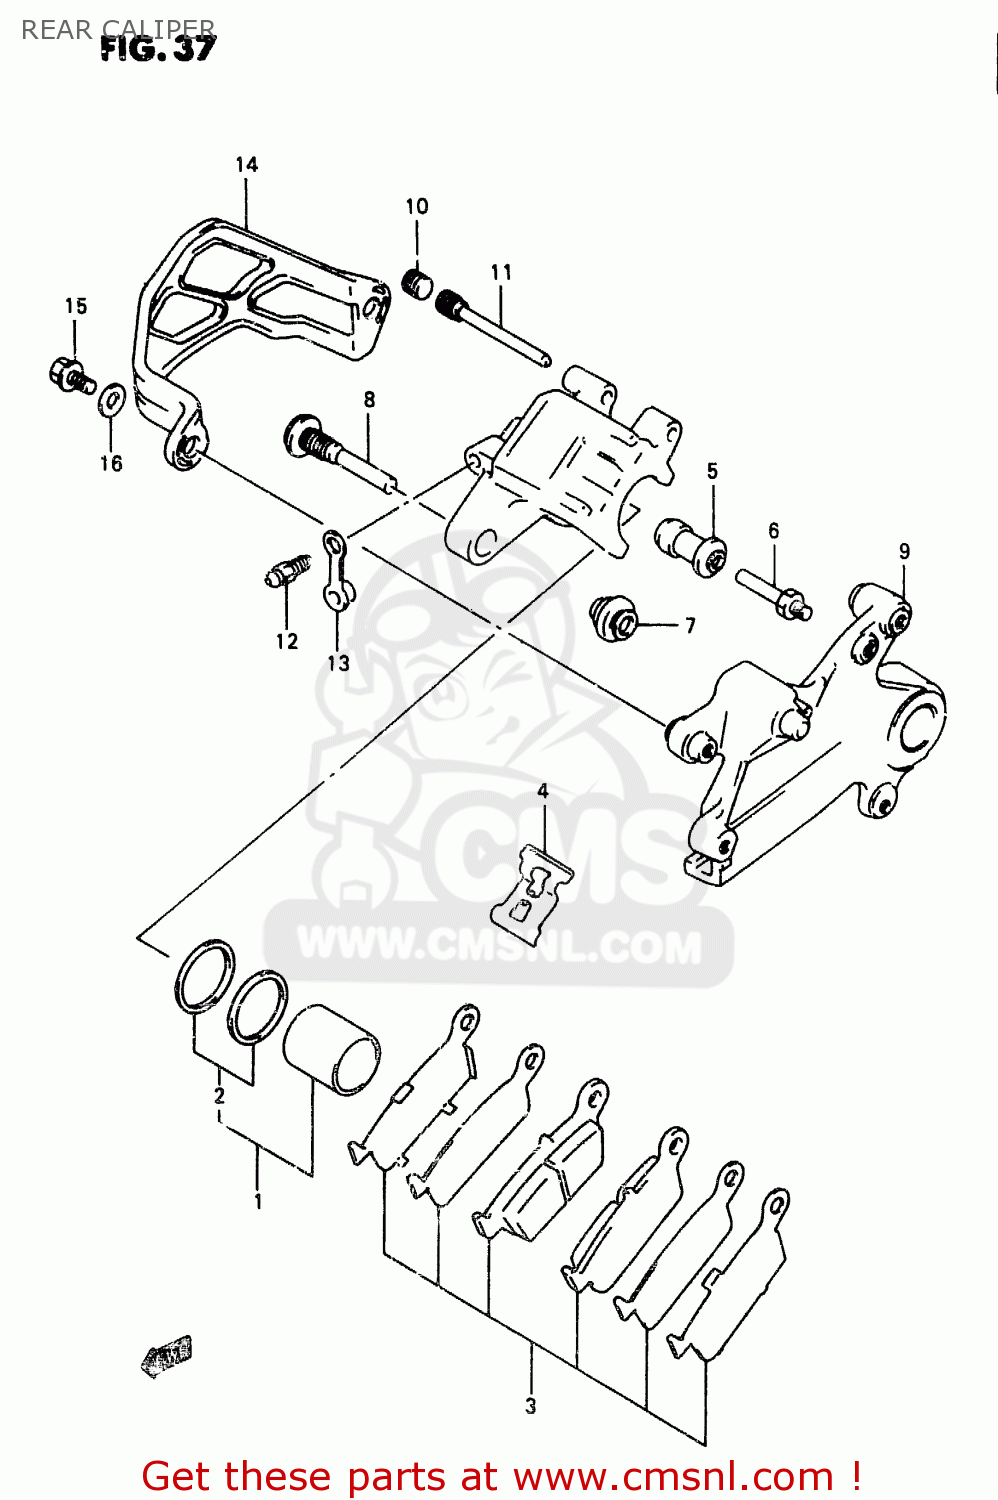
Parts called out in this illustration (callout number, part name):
1	PISTON SET
2	SEAL SET,PISTON
3	PAD & RETAINER SET
4	SPRING,PAD
5	BOOT
6	PIN,BOLT
7	BOOT
8	PIN,BOLT
9	BRACKET
10	PLUG,PIN
11	PIN,HANGER
12	BLEEDER
13	CAP,BLEEDER
14	GUARD,RR CALIPER
15	BOLT
16	WASHER
